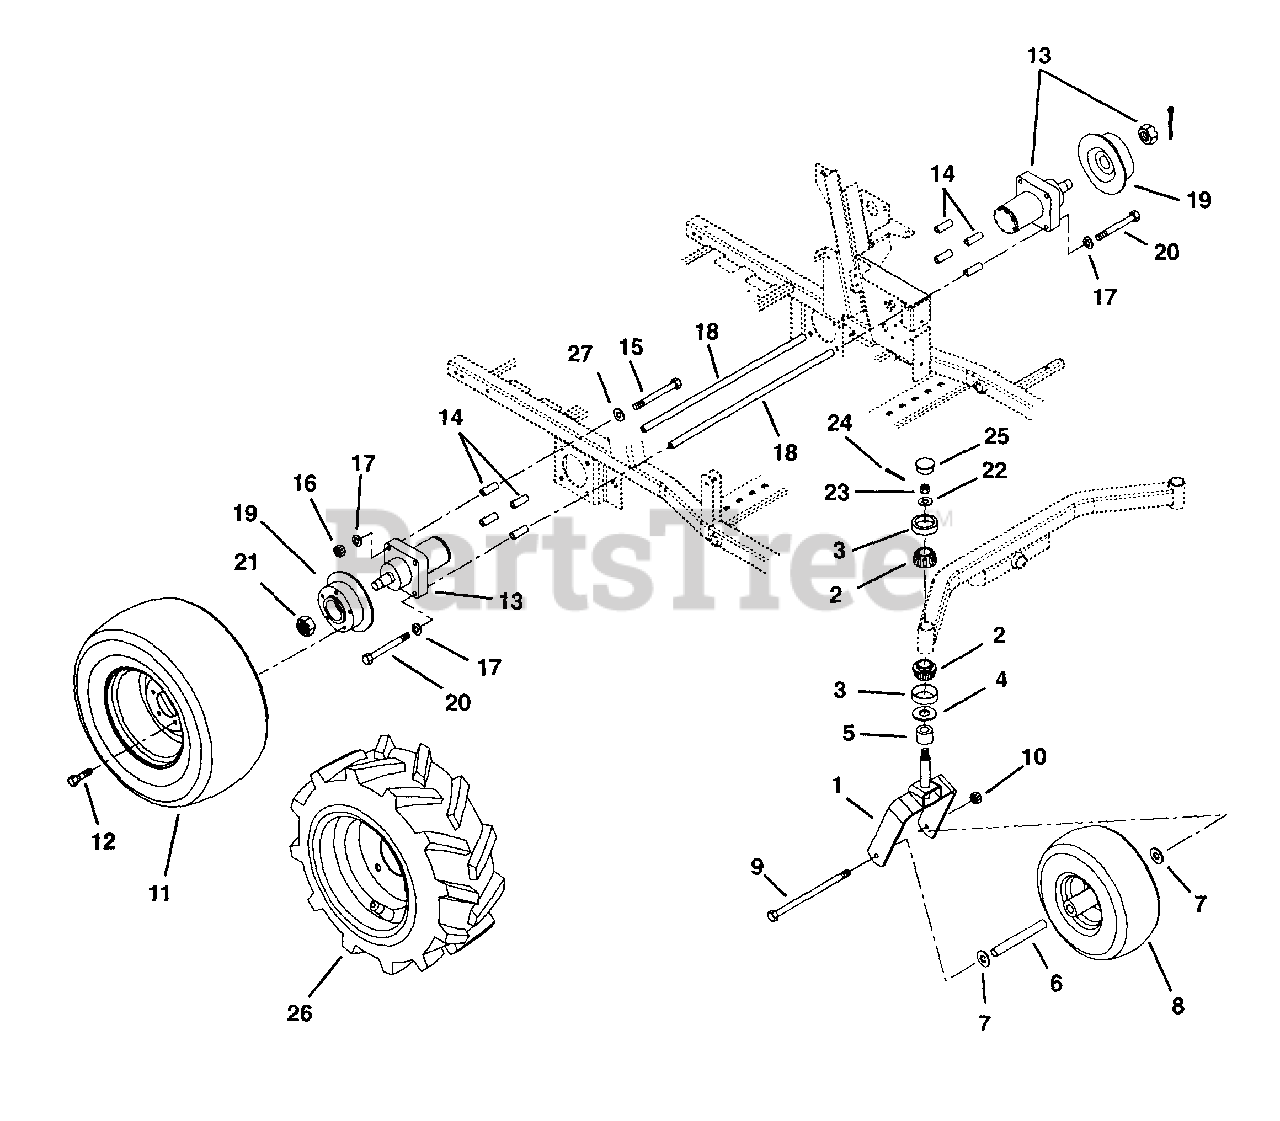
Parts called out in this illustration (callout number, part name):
1	Fork-Front
2	Bearing-Cone w/ Grease
3	Bearing-Cup 1.980 x .420
4	Bearing Seal 1.5 x 2 x .18
5	Spacer, PM, 1.03 I.D. x 1.5 O.D. x .375
6	Spacer-Wheel
7	Washer-Flat-Steel .515 x 1.625 x .250
8	Wheel/Tire 15 x 6 - 6
8	Tire 15 x 6 - 6
9	Bolt-Hex .50-13 x 9.00 Grade 5
10	Nut-Locking-Center .50-13
11	Wheel-Tire 23 x 10.50 - 12 Multi-Trac
11	Tire 23 x 10.50
11	Wheel-Tire 23 x 8.50 Multi-Trac
11	Tire 23 x 8.50
12	Bolt-Lug .50-20 x 1.62
13	Hydraulic Wheel Motor
14	Bushing-Sleeve .513 x .748 x 2.129
15	Bolt-Hex .50-13 x 5.00 Grade 5
16	Nut-Locking-Center .50-13
17	Washer-Locking .50 x .1 25
18	Rod-Motor Connecting
19	Hub and Disc
20	Bolt-Hex .50-13 x 4.50 Grade 5
21	Nut -Lock Jam Patch
22	Washer-Flat-Steel .755 x 1.375 x .062
23	Nut-Slotted .75-16
24	Pin-Cotter .16 x 1.00
25	Cap-Dust
26	Wheel/Tire Kit, 2602 L. 8 R.
26	Wheel/Tire-L.H. 23 x 10.5-12 Tru Power
26	Wheel/Tire-R.H. 23 x 10.5-12 Tru Power
26	Wheel/Tire 23 x 10.50 - 12 Tru Power
27	Spacer .500 x .750 x,321
